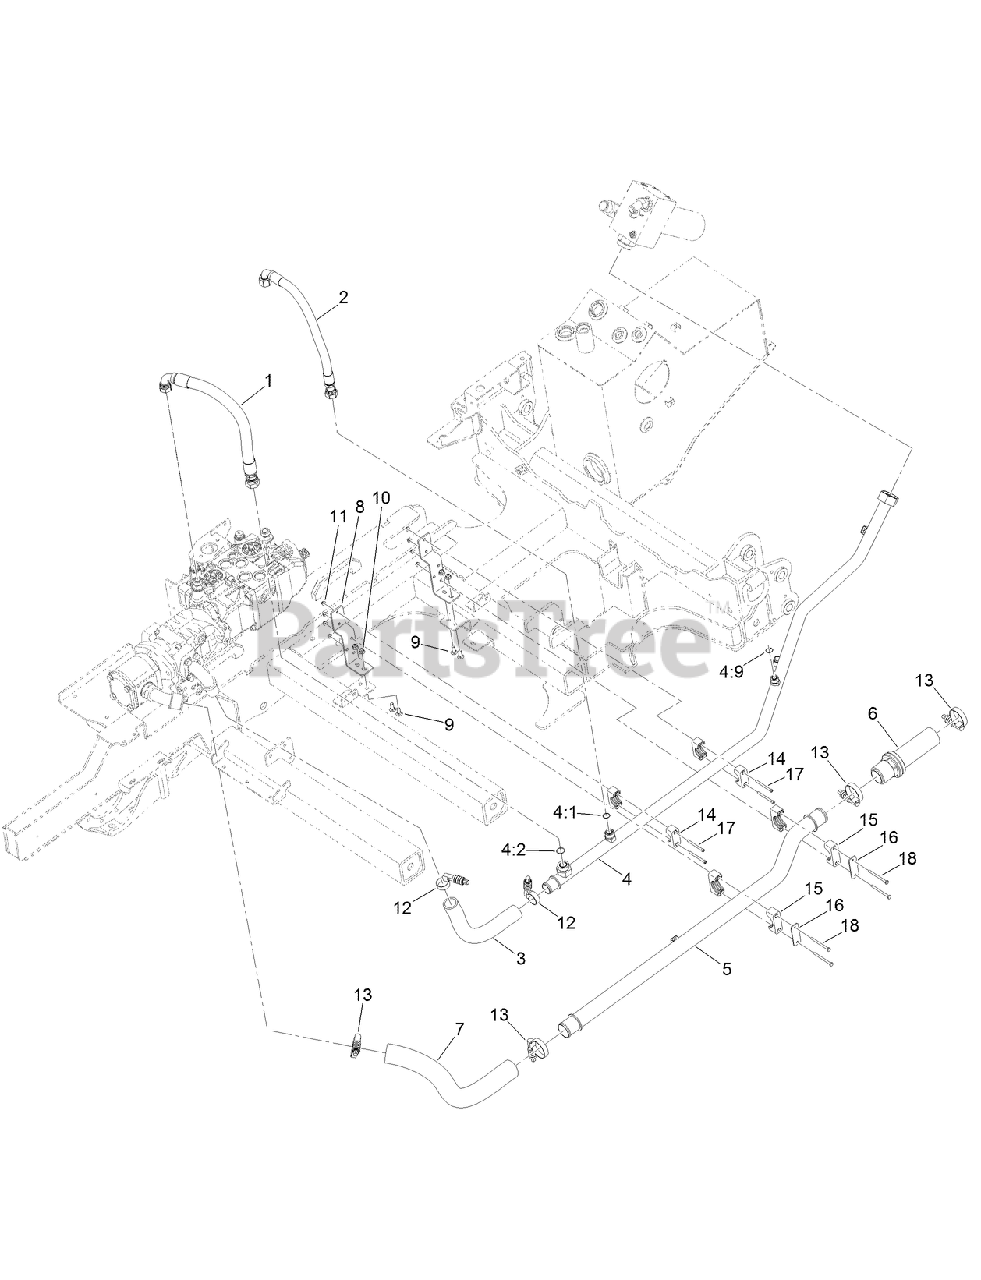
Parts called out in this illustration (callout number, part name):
1	HOSE ASM-HYD
2	HOSE ASM-HYD
3	HOSE-HYDRAULIC
4	TUBE ASM
4:1	O-RING
4:2	O-RING
4:9	O-RING
5	TUBE ASM-HYD
6	HOSE-HYDRAULIC
7	HOSE HYDRAULIC
8	BRACKET-HANGER, SUCTION LINE
9	SCREW-HH
10	NUT-HF, NI
11	NUT-HF
12	CLAMP-TORQUE, CONSTANT
13	CLAMP-TORQUE, CONSTANT
14	CLAMP-TUBE
15	CLAMP-TUBE
16	PLATE-COVER, CLAMP
17	SCREW-HSH
18	SCREW-HH
